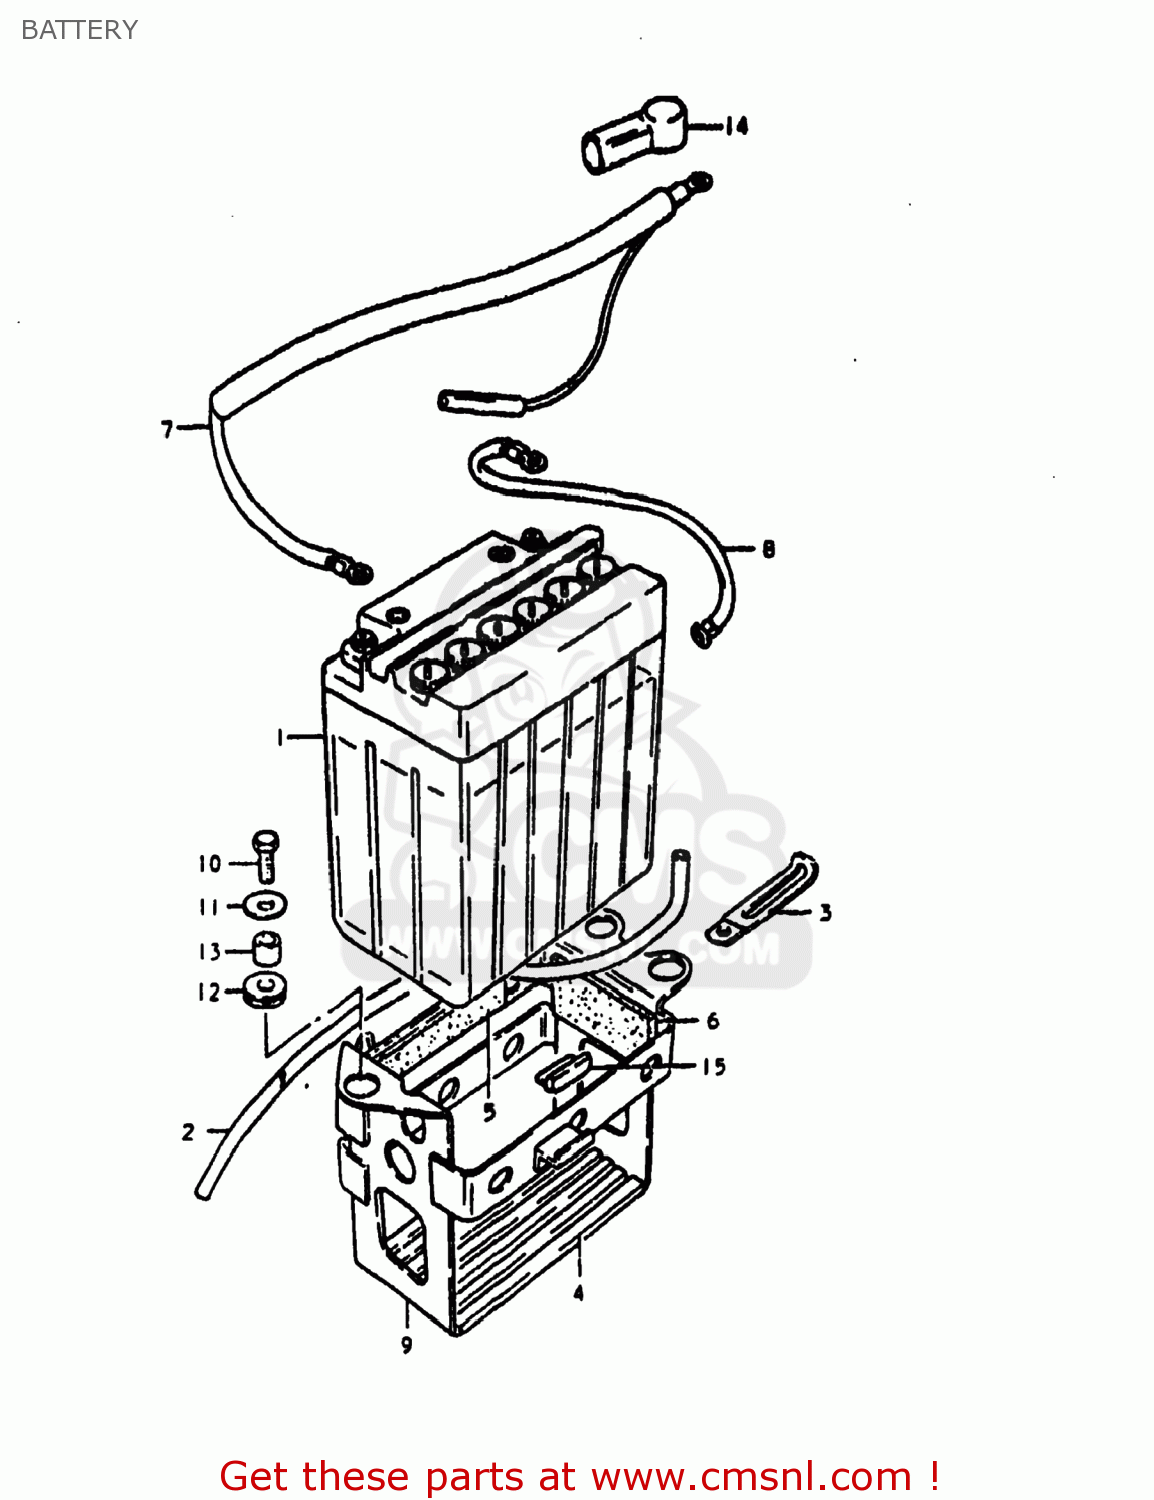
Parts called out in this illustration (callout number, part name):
1	BATTERY ASSY (12V)
2	HOSE,BATTERY EXHAUST
3	CLAMP L:35
4	PROTECTOR,BATTERY
5	PROTECTOR(20X90)X4
6	PROTECTOR,BATTERY
7	WIRE,BATTERY PLUS
8	LEAD WIRE,BATTERY(-)
9	HOLDER,BATTERY
10	BOLT, UPPER
11	WASHER
12	CUSHION
13	SPACER(6.1X9X7.5)
14	CAP,TERMINAL
15	CUSHION,FRAME COVER
